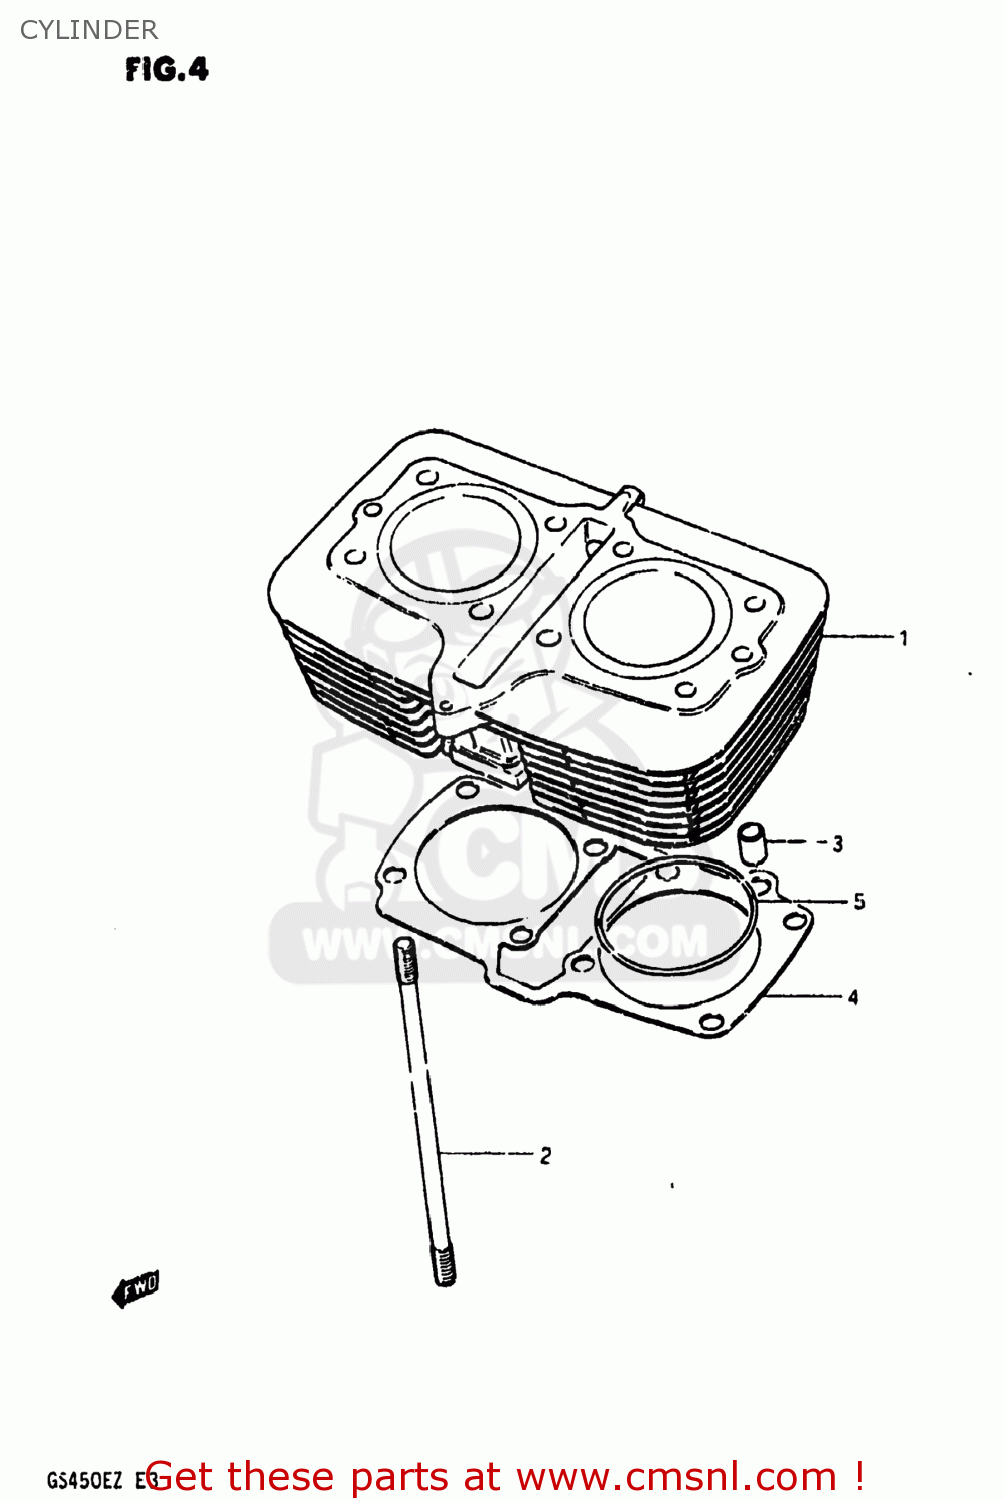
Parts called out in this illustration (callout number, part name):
1	CYLINDER
2	STUD
3	PIN
4	GASKET,CYLINDER (MCA)
5	O RING(D:2,ID:74)
